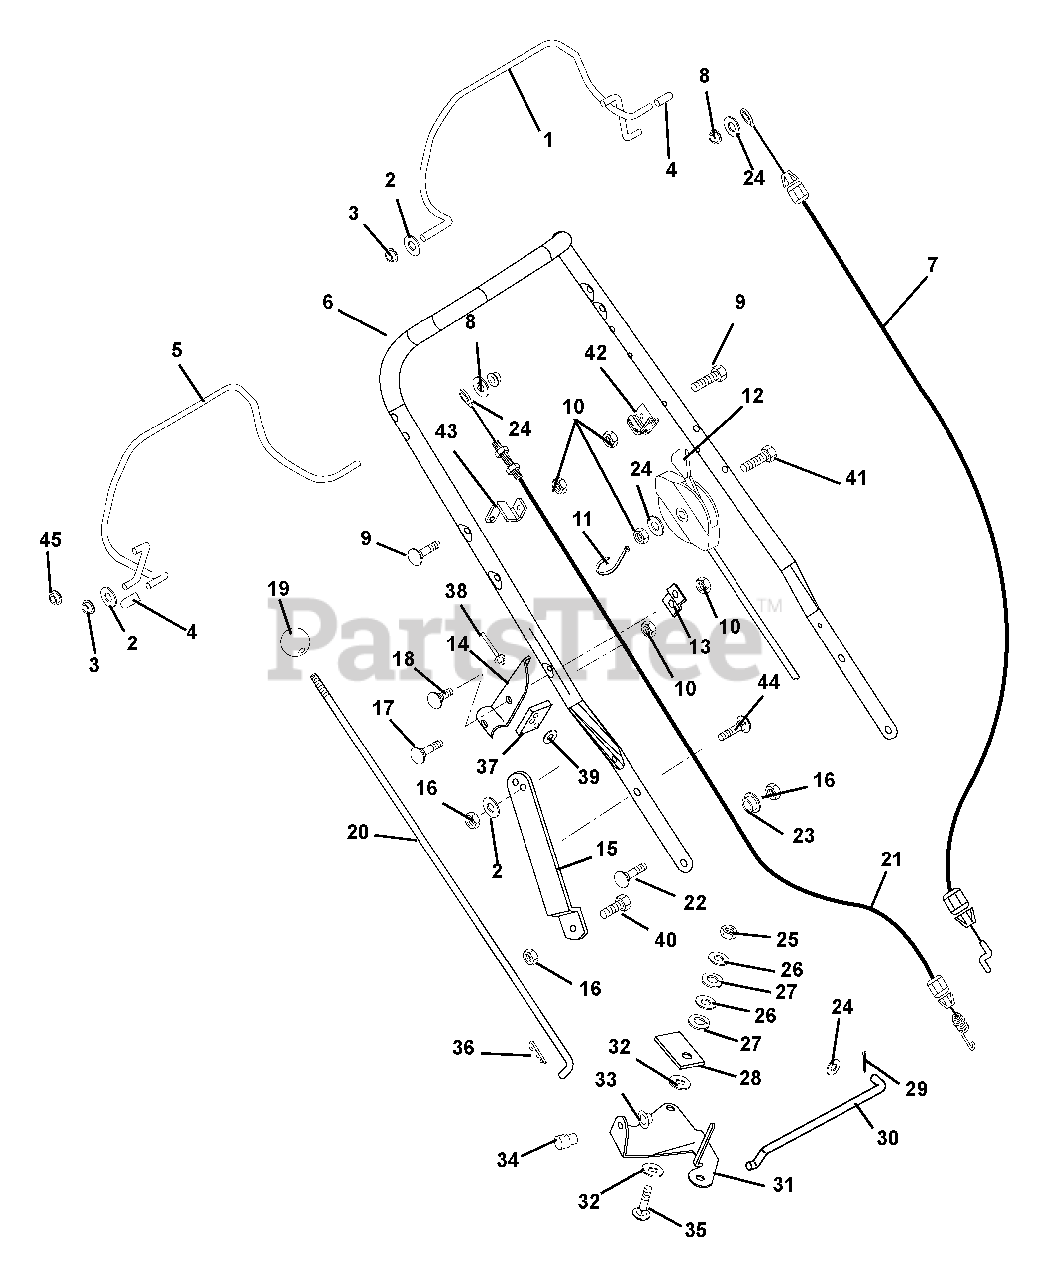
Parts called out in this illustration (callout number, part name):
1	BAIL, ENGINE WELDMENT
2	WSHR-FL-STL.344X.688X.065YWZC
3	BSHG-FLG .325X.444X.440X.560
4	CAP, VINYL, .25 ID
5	BAIL, TRACTION (WLDMENT)
6	BAR, WBLM HANDLE
7	CABLE, ENGINE
8	RG-RTNG-EXT .250X.010
9	BLT-RDHDXLSQNK.25-20X1.25 G5YZ
10	NUT-LK-CTR .25-20 YWZC
11	CABLE TIE LG 5-1/2
12	CONTROL - THROTTLE - HONDA
13	BRACE, SPEED CONTROL
14	BRACKET, SPEED CONTROL
15	BRACKET, HANDLEBAR
16	NUT-LK-CTR .31-18 YWZC
17	BLT-RDHDSQNK .25-20X1.50 G5YZ
18	BLT-RDHDSQNK .25-20X.50 G5YZ
19	KNOB, BALL 5/16-18 X 1.5
20	ROD-SPEED CONTROL
21	CABLE, WBLM TRACTION
22	BLT-RDHDSQNK .31-18X1.00 G5YZ
23	BSHG, FLG .325X.499X.26X.88
24	WSHR-FL-STL.281X.62X.065 YWZC
25	NUT-LK-CTR .38-16 YWZC
26	WSHR-FL-STL.406X.812X.065 YWZ
27	WSHR-LK .375X.115 HVY YWZC
28	PRESSURE FLANGE
29	PIN-CTR .06X.50 EXTPRSQCT YWZ
30	SHIFT LINK
31	BELL CRANK - SPEED CONTROL
32	FRICTION WASHER
33	CAP, 3/8 ROD YWZC
35	BLT-RHDSSQNK .38-16X1.25 G5YZ
36	PIN-HAIR INT .08X.18X1.18 YWZC
37	SUPPORT PAD
38	RVT .187X.575 DOME AL BLACK
39	WSHR-FL-STL.219X.50X.049 YWZC
40	BLT-HEX .31-18X.75 GR5 YWZC
41	BLT-HEX .25-20X2.50 GR5 YWZC
42	ANCHOR, WBLM ENGINE CABLE
43	ANCHOR, CABLE
44	BLT-RDHDSQNK .31-18X.75 G5YZ
45	NUT-PUSH .312 DIA. PAL
